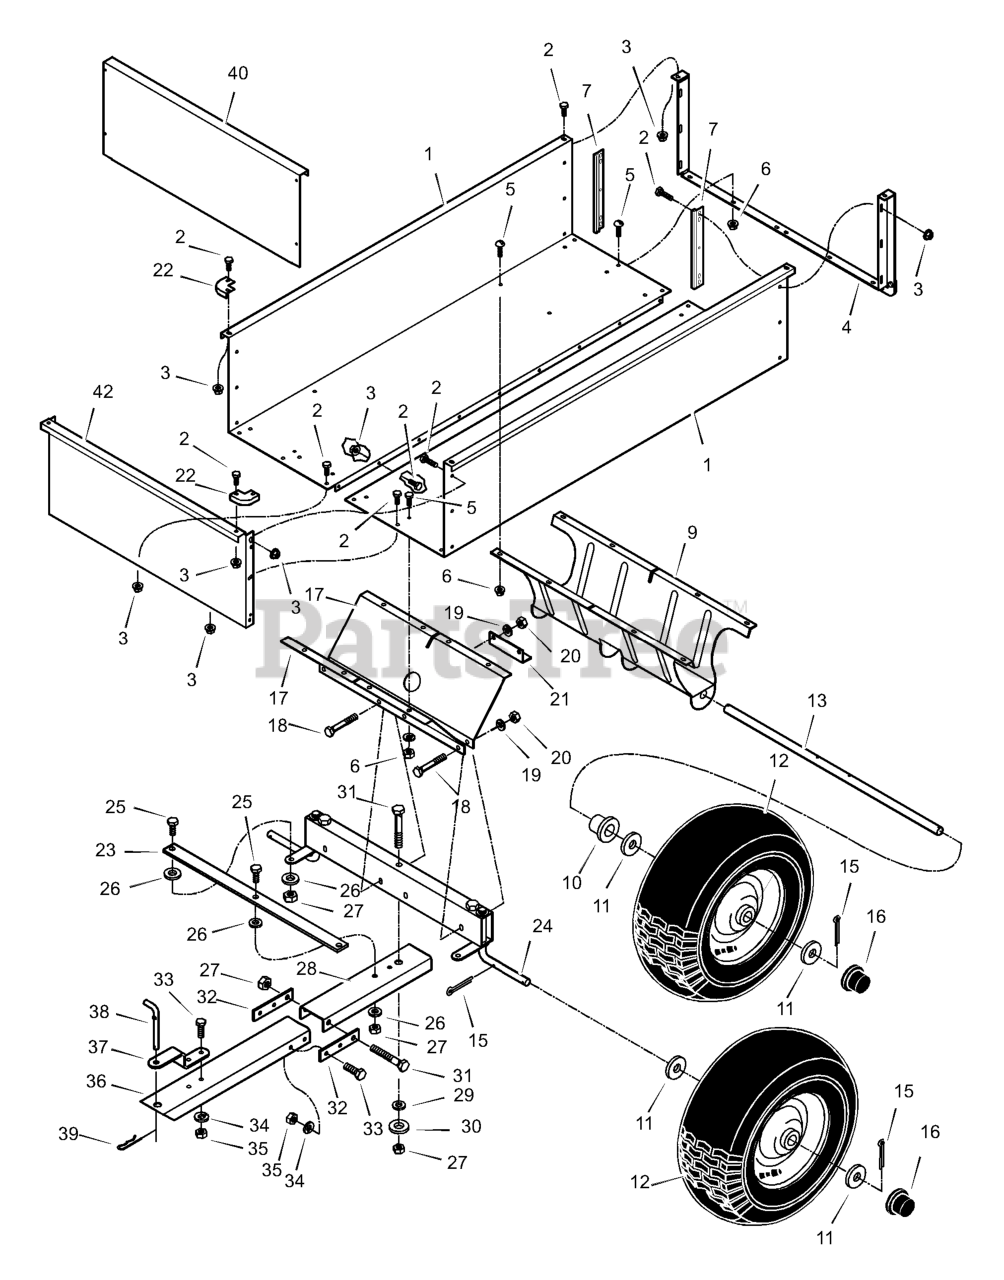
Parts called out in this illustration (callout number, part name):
1	Body Panels
2	Hex Bolt M6X15
3	Hex Nut M6, Sems
4	Tailgate Brace
5	Truss Head Bolt M8x20
6	Hex Nut M8, Sems
7	Tailgate Guide
9	Rear Wheel Support
10	Plastic Flange Bearing
11	Washer Flat (020 Large)
13	Axle, Rear
15	Cotter Pin 3x25
17	Front Axle Support
18	Hex Bolt M8x65
19	Lockwasher 08
20	Hex Nut M8
21	Tongue Reinforcement Angle
22	Front Corner Cap
23	Tie Rod
24	Axle Spindle
25	Hex Bolt M12x30
26	Washer Flat (012 Small)
27	Hex Lock Nut M12 Thread
28	Tongue, Rear Section
29	Pivot Bushing
30	Washer Flat (012 Large)
31	Hex Bolt M12x115
32	Pivot Bar
33	Hex Bolt M10x25
34	Lockwasher 010
35	Hex Nut M10
36	Front Tongue Section
37	Hitch Bracket
38	Hitch Pin
39	Hair Cotter Pin
40	Tailgate
42	Front Panel
